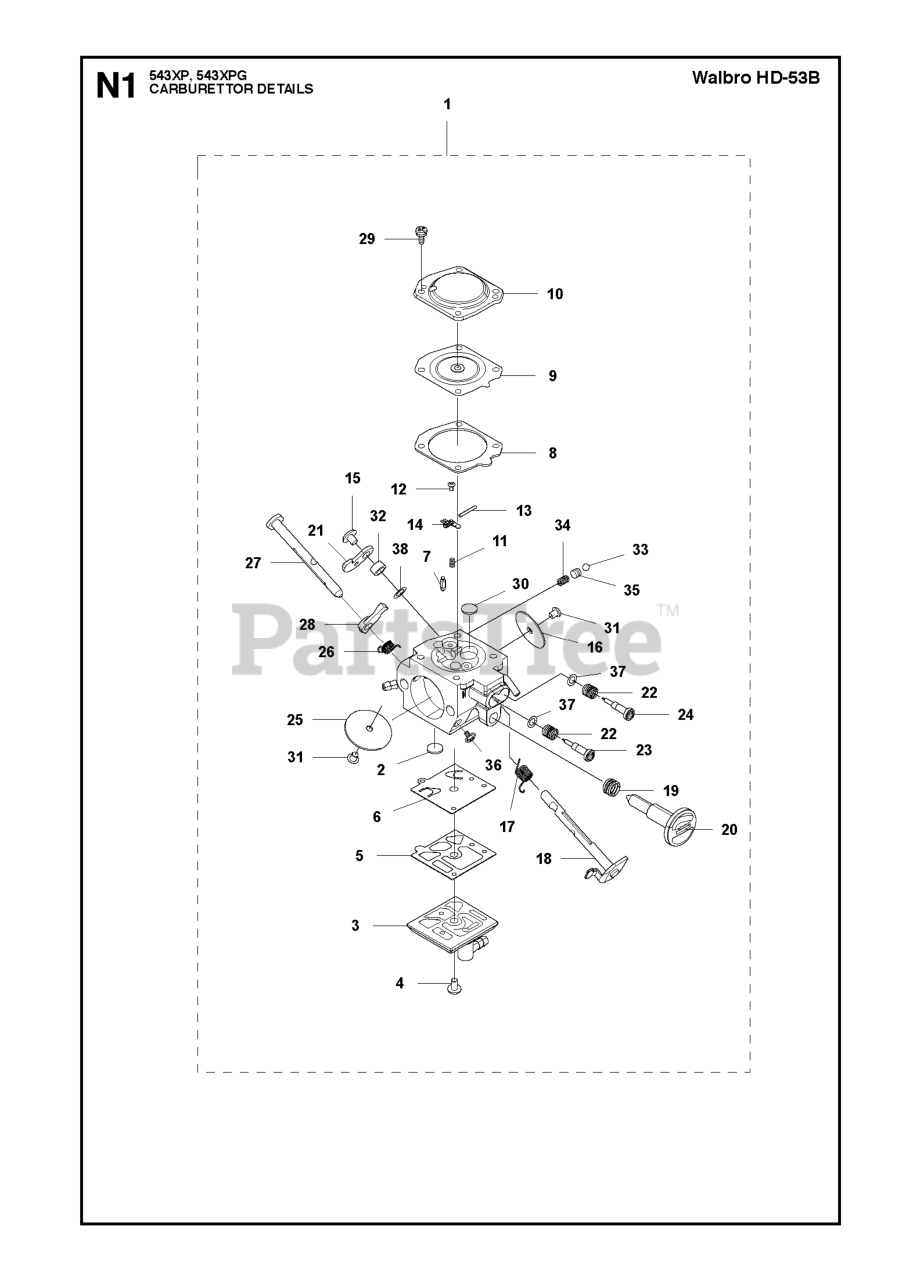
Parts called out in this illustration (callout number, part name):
1	CARBURETOR
2	SCREEN
3	COVER ASSEMBLY PUMP 21-3780
4	SCREW Z149181130
6	95-75 DIAPHRAGM Z335081260
7	VALVE INLET
9	DIAPHRAGM ASSEMBLY METERING 95
16	VALVE THROTTLE 34-314
17	SPRING 98-3706
18	SHAFT ASSY THROTTLE
21	LEVER THROTTLE 18-3551
23	NEEDLE HIGH SPEED
24	NEEDLE IDLE
25	VALVE CHOKE 34-3504
26	SPRING 98-3718
27	SHAFT ASSY CHOKE 22-4356
28	LEVER FAST IDEL 18-3566
29	SCREW ASSY
31	SCREW 96-3240
35	PISTON ASSY
